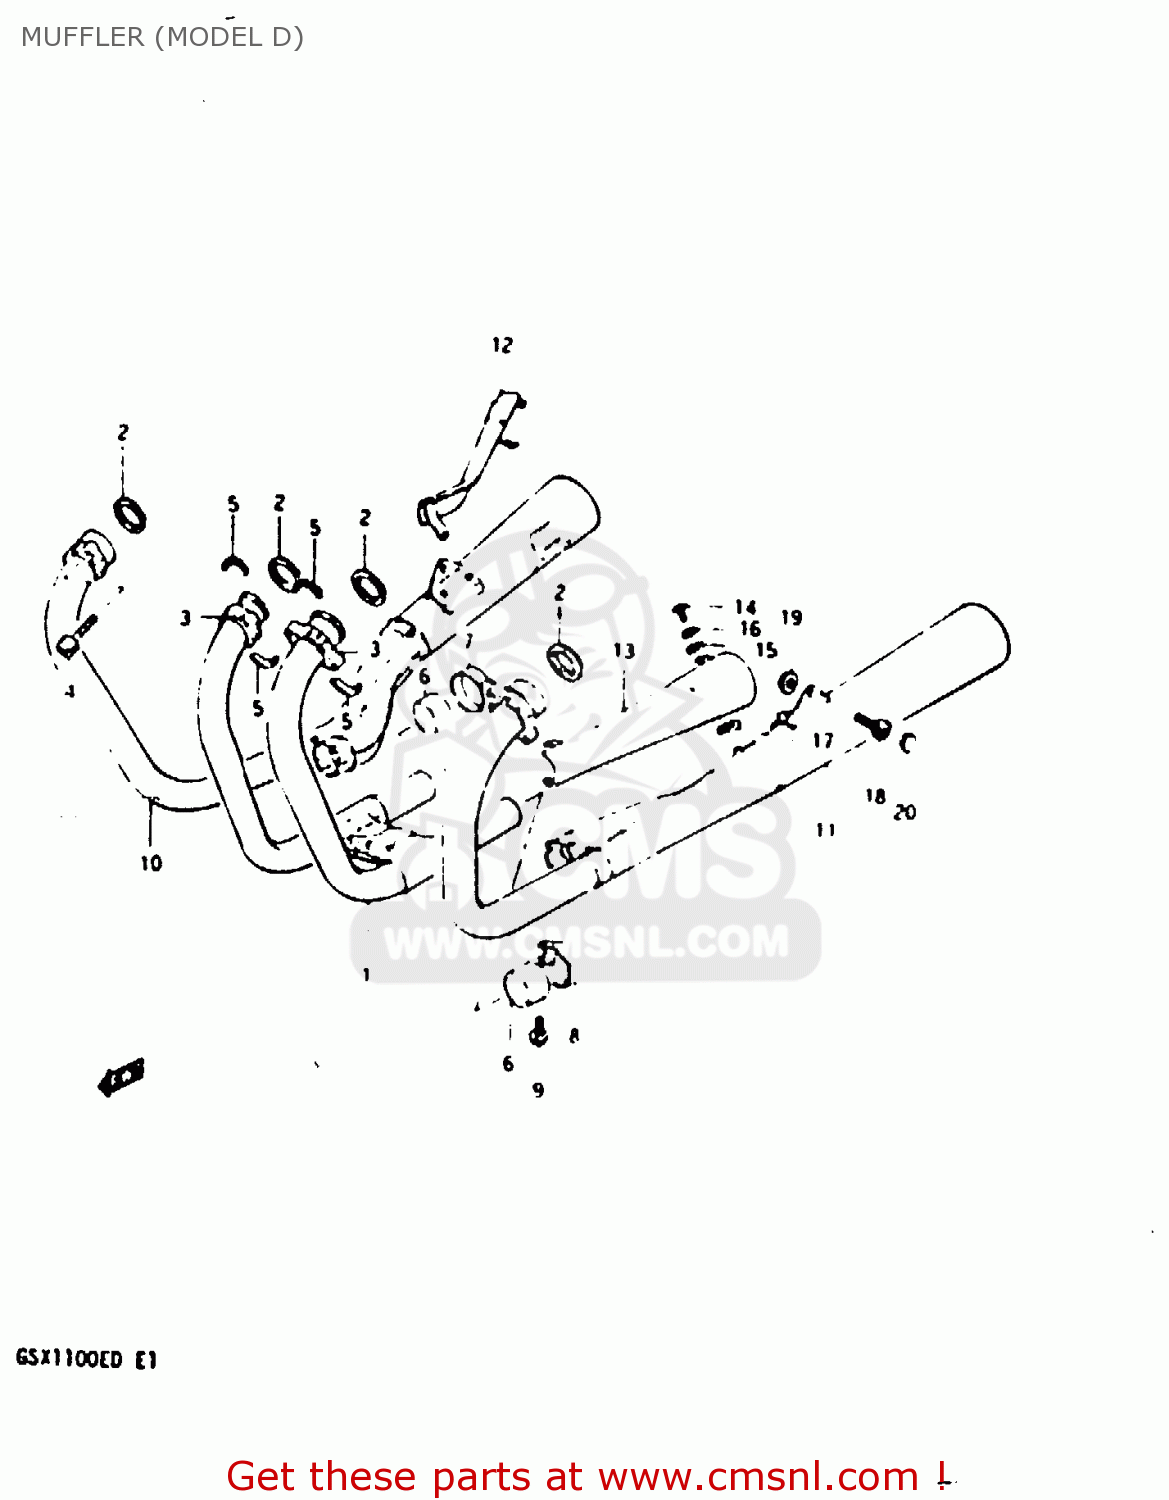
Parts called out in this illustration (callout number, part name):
1	PIPE,EXHAUST,CENTER
2	GASKET,EXHAUST PIPE (NAS)
3	CLAMP(H:21)
4	BOLT
5	PLATE,EXHAUST P
6	CONNECTOR,MUFFLER
7	CLAMP,MUFFLER CONNECTOR,R
8	CLAMP,MUFFLER CONNECTOR,L
9	BOLT
10	MUFFLER, RH
11	MUFFLER, LH
12	COVER,MUFFLER
13	COVER,MUFFLER
14	SCREW
15	WASHER
16	LOCK WASHER
17	GASKET 6.2X12X1.5 (MCA)
18	BOLT
19	NUT
20	CAP
